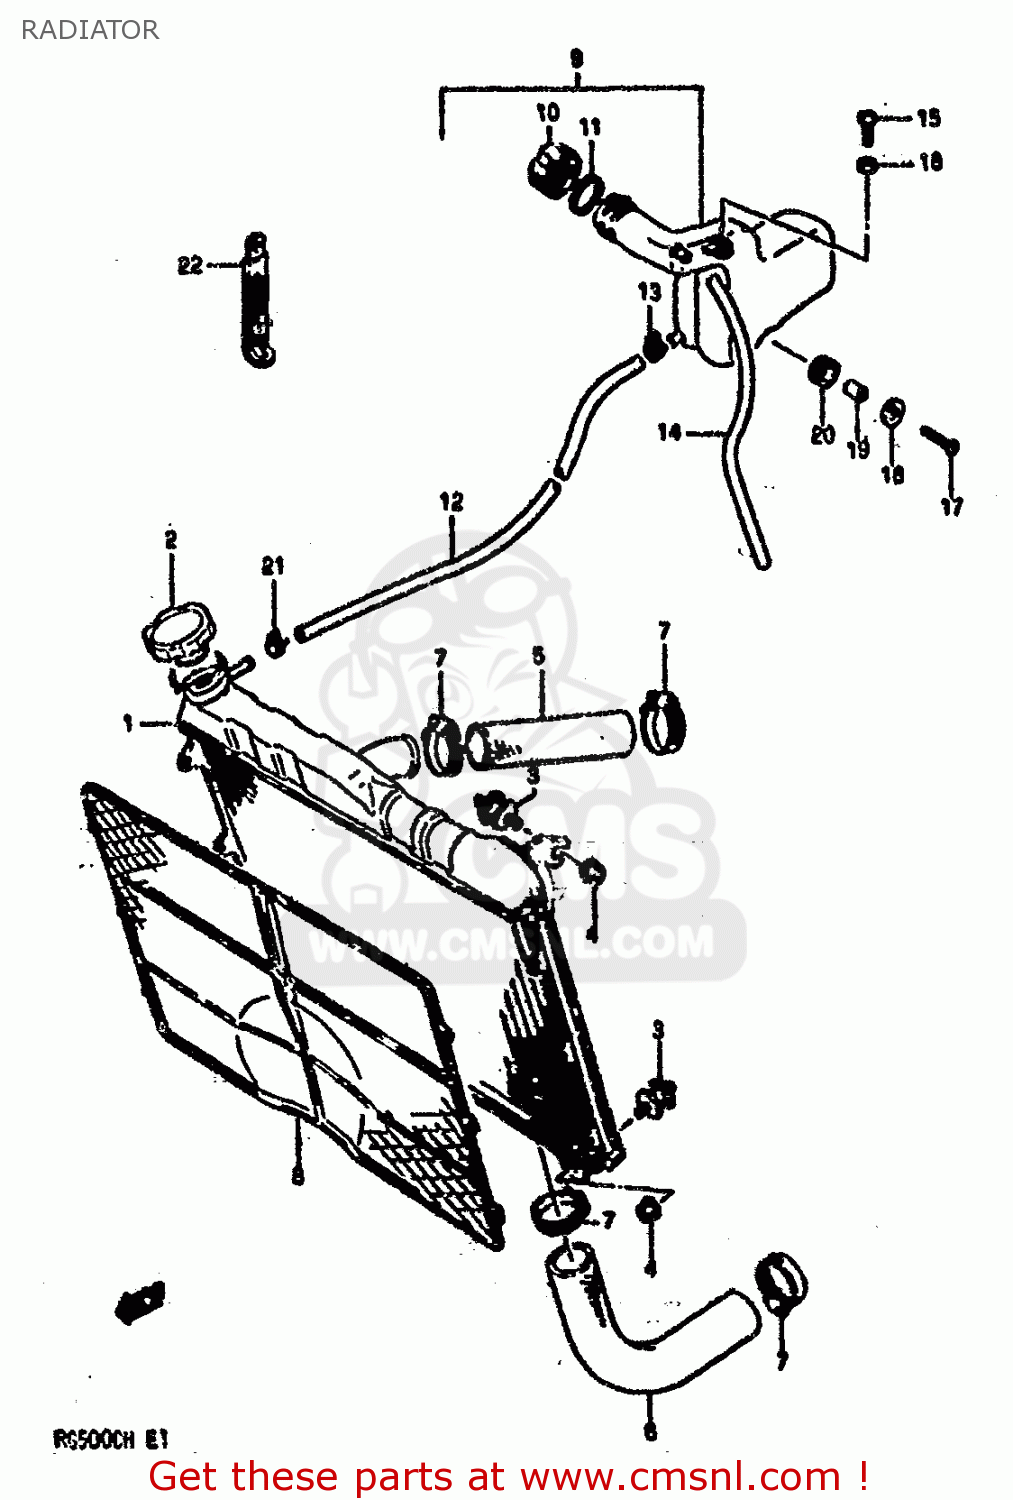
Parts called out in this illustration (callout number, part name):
1	RADIATOR
2	CAP,RADIATOR
3	BOLT,RADIATOR CUSHION
4	NUT 6MM
5	HOSE,RADIATOR INLET
6	HOSE,RADIATOR OUTLET
7	CLAMP
8	NET,RADIATOR
9	TANK ASSY,RESERVOIR
10	CAP,RESERVOIR TANK
11	GASKET,RESERVOIR TANK CAP (NAS)
12	HOSE
13	CLIP
14	HOSE, INLET
15	SCREW
16	WASHER (6.5X18X1.6)
17	SCREW
18	WASHER (6.5X20X1.2)
19	SPACER (6.5X10.5X13.5)
20	CUSHION
21	CLIP
22	CLAMP
